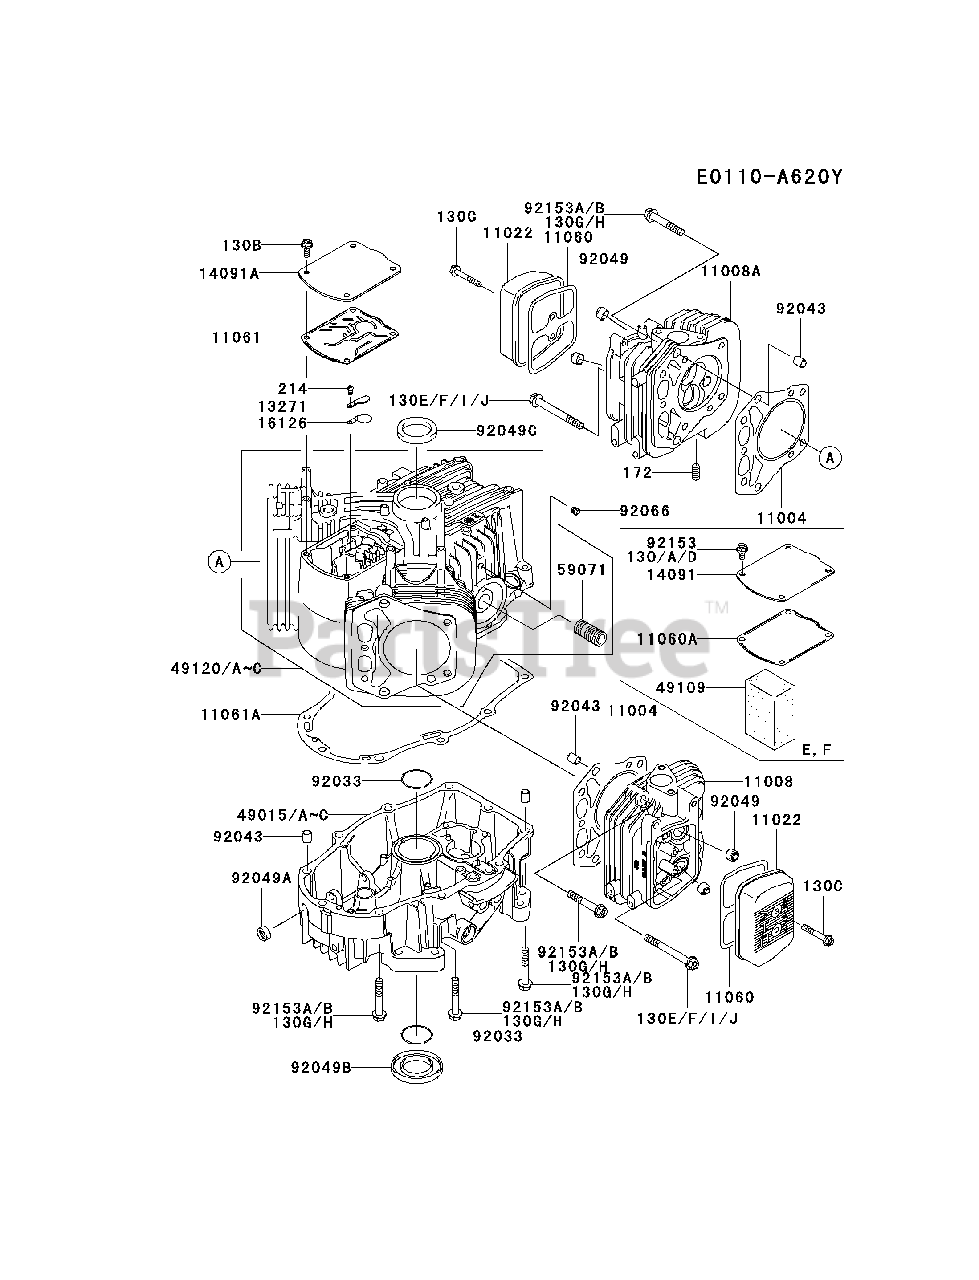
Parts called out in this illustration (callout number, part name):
130F	BOLT-FLANGED,8X75
130H	BOLT-FLANGED,8X50
130J	BOLT-FLANGED,8X75
172	BOLT-STUD,8X18
214	SCREW-PAN+-,4X8
